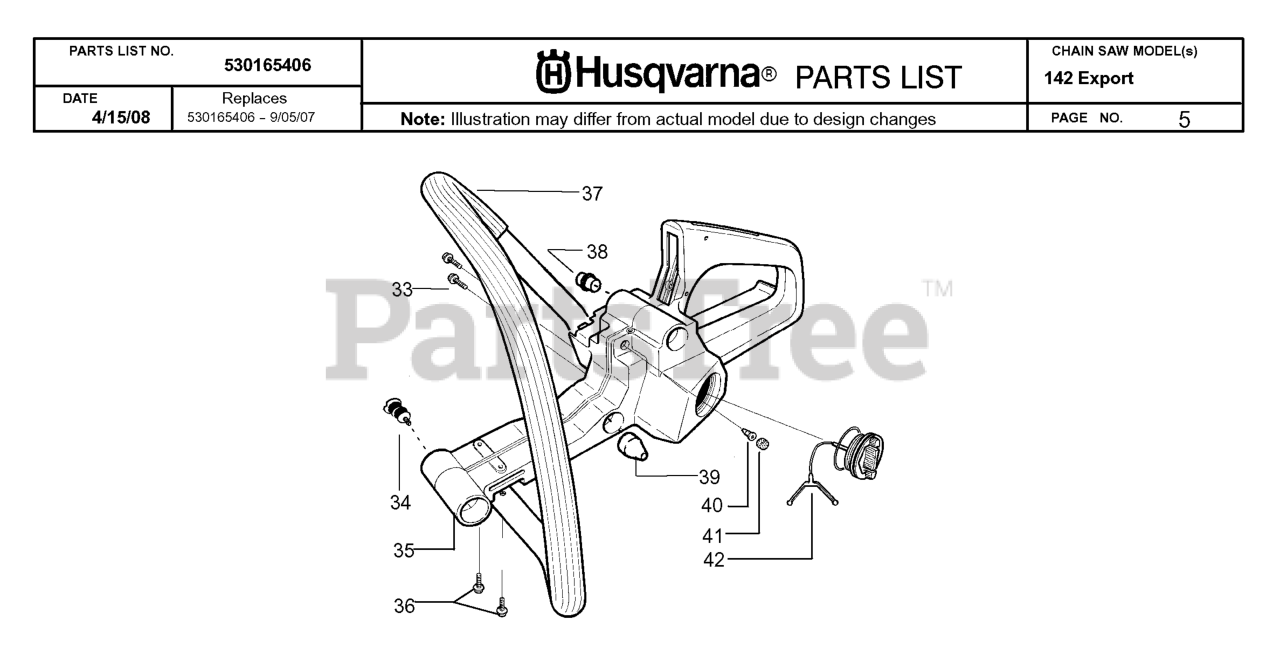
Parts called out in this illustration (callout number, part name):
37	HANDLE FRONT
38	FRONT HANDLE ISOLATOR
39	SHOCK MOUNT(X2) 36/41
40	VALVE-CHECK (DUCKBILL)
41	BRONZE PLUG
42	FUEL CAP KIT
